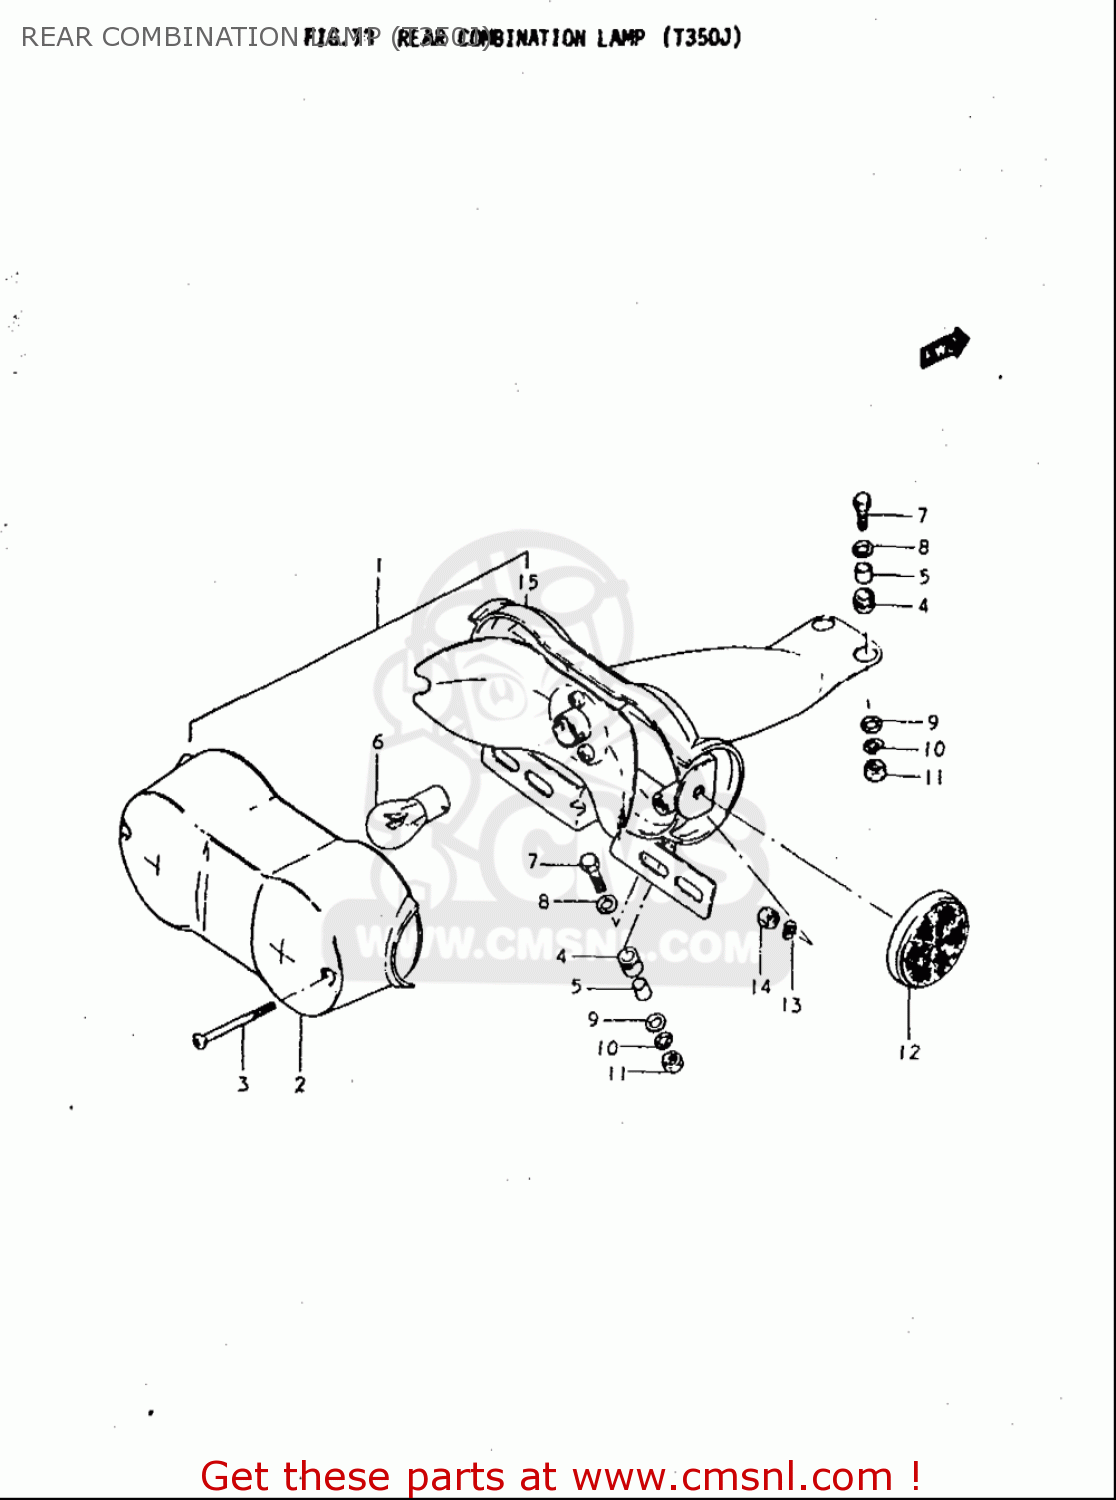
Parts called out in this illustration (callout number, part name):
2	LENS,RR COMBINATION LAMP
3	SCREW
4	CUSHION
5	SPACER
6	BULB(12V23W)
7	BOLT 6X23
8	WASHER(6.5X18X1.6)
9	WASHER
10	WASHER,LOCK
13	WASHER,LOCK
14	NUT
